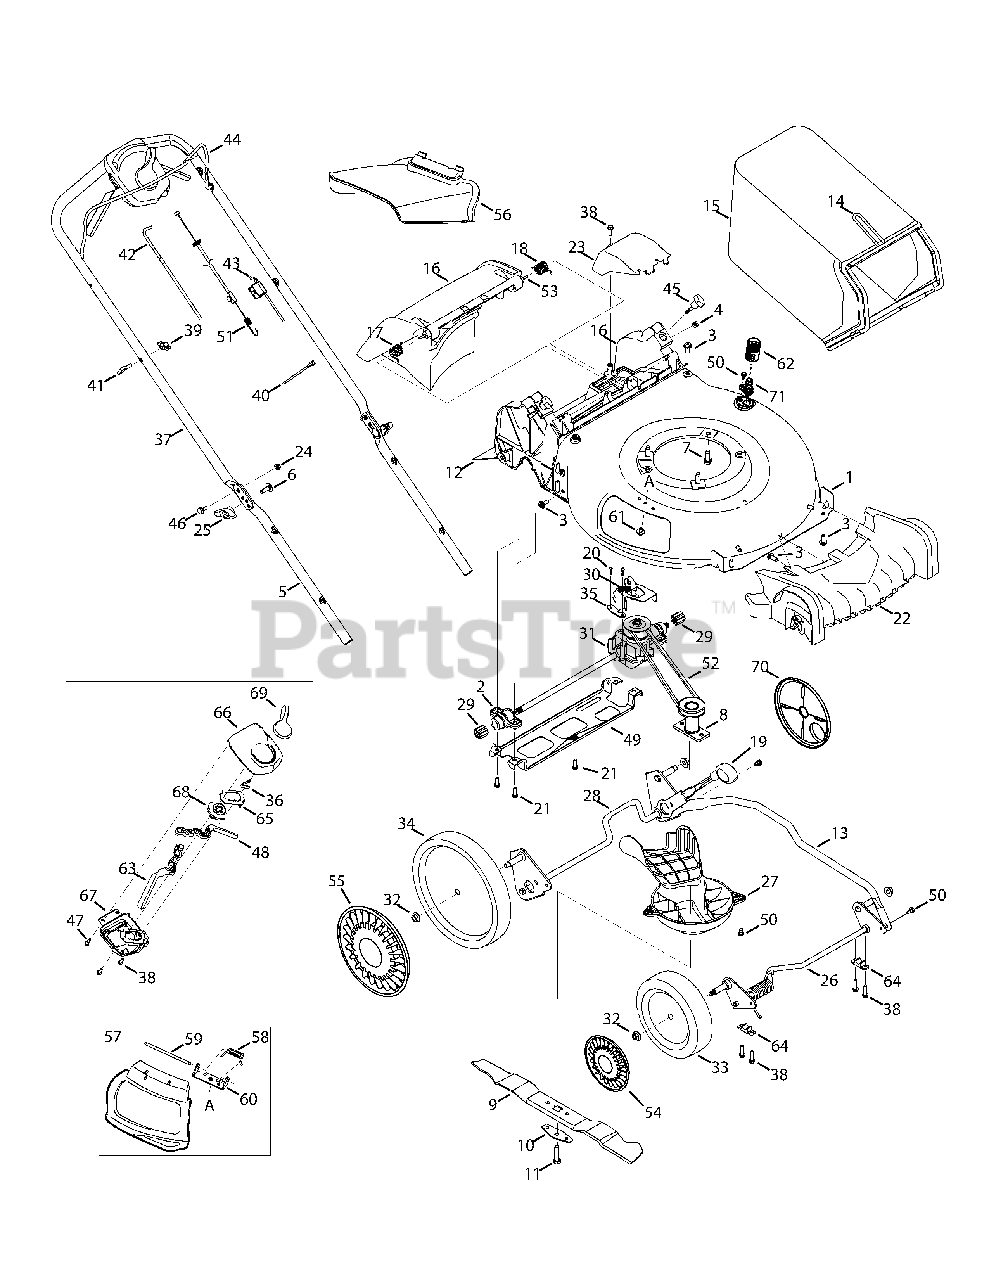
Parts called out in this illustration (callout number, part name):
1	Deck, 21" w/ deck wash
2	Bearing Assembly
3	Screw, 5/16-14 x .750
4	Nut, Sq., 1/4-20
5	Lower Handle
6	Carriage Screw ,5/16-18
7	Screw, 3/8-16 x 1.00
8	Blade Adapter
9	Mulching Blade
10	Blade Bell Support
11	Screw, 3/8-24 x 1.50
12	Trailing Shield
13	Cross Bracket
14	Grass Catcher Frame
15	Grass Bag
16	Rear Discharge Door Assembly
17	Torsion Spring - RH
18	Torsion Spring - LH
19	Adjustment Lever Knob, Red
20	Screw, .159 x .43 Hex Washer
21	Screw, 1/4-15 x 1.25
22	Front Cover
23	Transmission Cover
24	Nut, Flange Lock, 1/4-20
25	Wing Knob
26	Front Axle Assembly
27	Engine Baffle
28	Rear Axle Assembly
29	Spur Gear, 9T
30	Exten. Spring, 2.675
31	Transmission Assembly
32	Flange Lock Nut, 3/8-16
33	Front Wheel
34	Rear Wheel
35	Transmission Bracket
36	Spring
37	Upper Handle
38	Screw, 1/4-15 x .750
40	Cable Tie
41	Rope Guide
42	Drive Cable
43	Control Cable (Kohler)
44	Blade Control
45	Wing Nut
46	Sldr. Screw, .375 x .126 x 1/4-20
47	Scr., Shldr, 1/4-15 x .970
48	Control Lever LH
49	Rear Support Bracket
50	Shoulder Screw, 1/4-20 x 0.50
51	Speed Adjustment Cable
52	V-Belt
53	Pivot Rod
54	Hubcap, Grey
55	Hubcap, 11", Grey
56	Side Discharge Chute
57	Mulch Plug (Incl. 58-60)
58	Torsion Spring
59	Hinge Pin
60	Chute Deflector Bracket
61	Screw, 1/4-20 x .500
62	Water Nozzle Adapter
63	Control Lever RH
64	Bushing, Lock, .505 Dia. X .62
65	Cable Adjust Plate
66	Upper Housing
67	Lower Housing
68	Speed Adjust Actuator
69	Speed Selec Lever
70	Wheel Dust Cover
71	Water Nozzle
